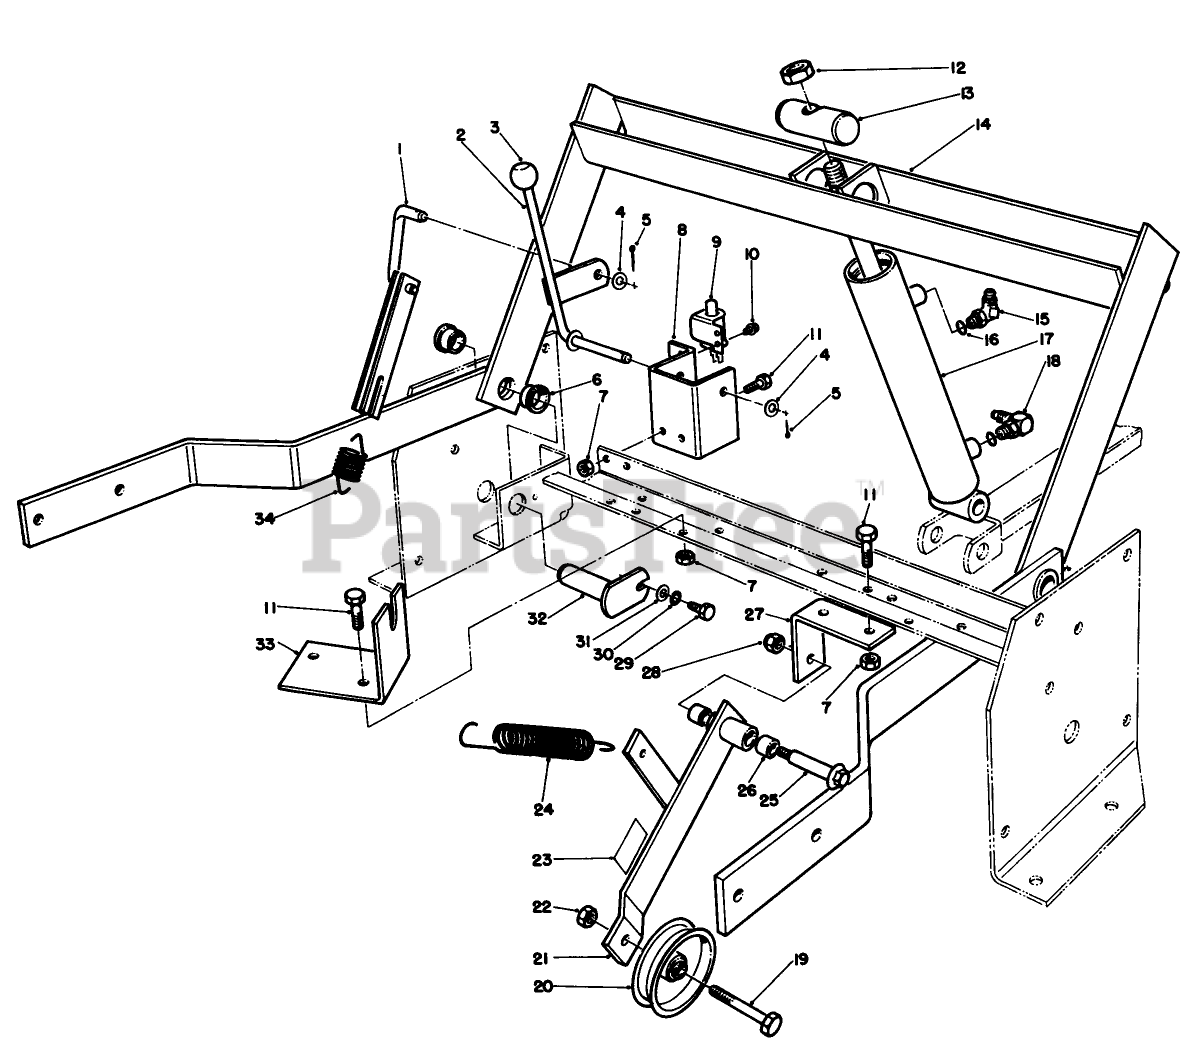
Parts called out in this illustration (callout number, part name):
4	WASHER-FLAT
5	PIN-COTTER
6	BEARING-FLANGE
7	NUT-LOCK, NI
9	SWITCH-BRAKE, PARKING
10	SCREW-TAPTITE
11	SCREW-HH
12	NUT-JAM
13	CYL.PIVOT PIN
15	FITTING-45 DEG
16	O-RING
17	CYLINDER - LIFT
18	FITTING-ELBOW, 90
19	SCREW-HH
21	IDLER LEVER ASM
22	NUT-LOCK, NI
23	DECAL-WARNING
24	IDLER EXT SPRING
25	BOLT-WHEEL
26	BUSHING
27	JACKSHFT IDLR BRKT
28	NUT-LOCK
29	SCREW-HH
30	SCREW-HH
31	WASHER-FLAT
34	PARK BRAKE SPRING
